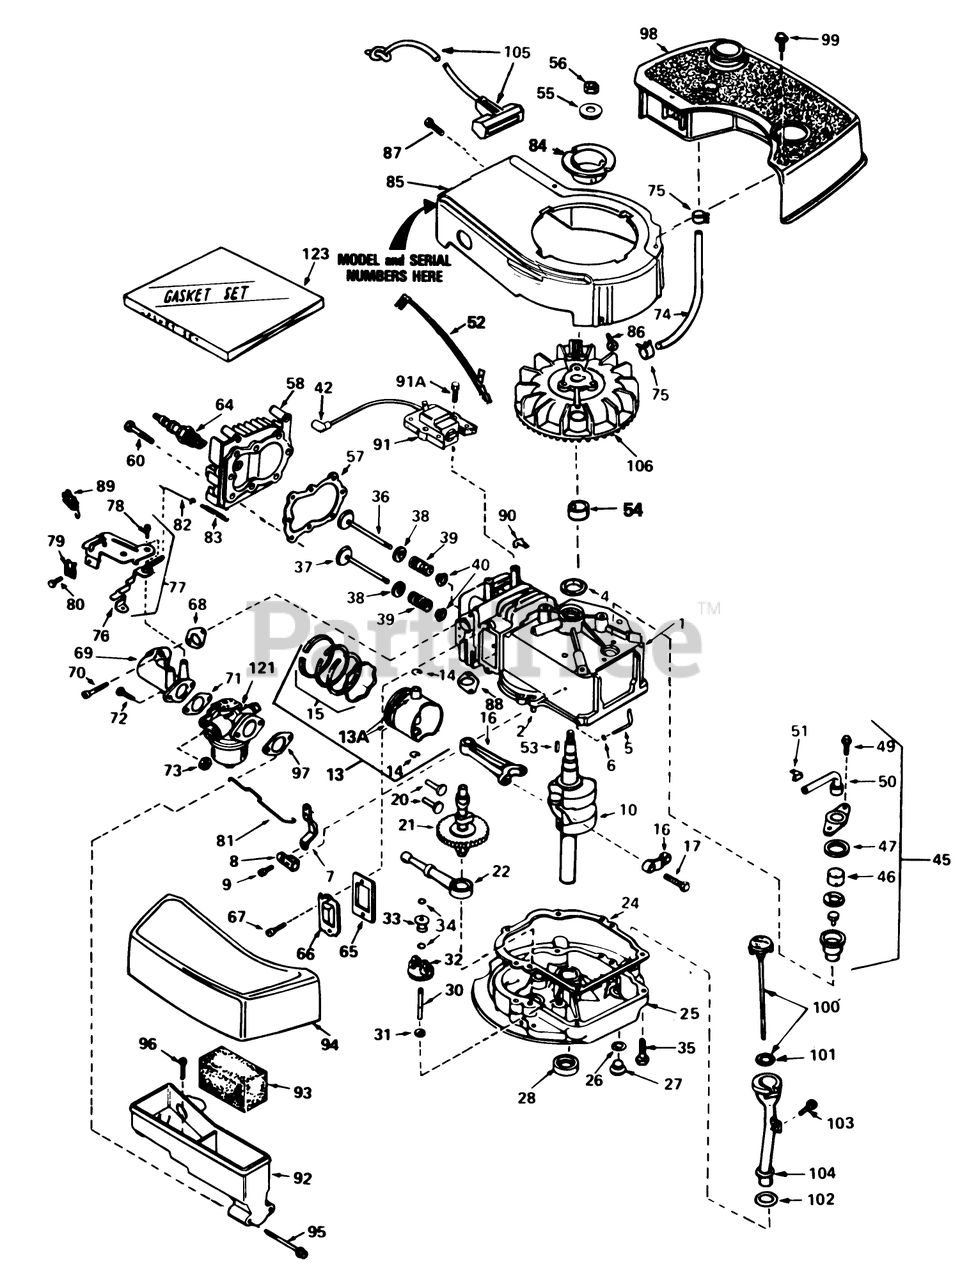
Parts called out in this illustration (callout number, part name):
1	Cyiinder Assy. (Incl. Ref. #2, 4 105)
2	Pin-Dowel
4	Seal-Oil
5	Rod, Governor (Incl. No. 36)
6	Washer-Flat
7	Governor Lever
8	Clamp-Lever, Governor
9	Screw
10	Crankshaft
13	Piston, Pin Ring Assy. (Std.) (Incl. Ref. #13A, 14 15)
13	Piston, Pin Ring Assy. (.010 oversize) (Incl. Ref. #13A, 14 15)
13	Piston, Pin Ring Assy. (.020 oversize) (Incl. Ref. #13A, 14 15)
13A	Piston Pin Assy. (Incl . Ref. . #14) (Std.)
13A	Piston Pin Assy. (Incl. Ref. #14) (.010 Oversize)
13A	Piston Pin Assy. (.020 oversize) (Incl. Ref. #14)
14	Ring-Retaining, Piston Pin
15	Ring Set (Std.)
15	Ring Set (.020" OS)
15	Ring Set (.010" OS)
16	Rod Assy., Connecting (Incl. Ref. #17)
17	Bolt-Rod, Connecting
20	Lifter-Valve
21	Camshaft(Mech.Comp. Release)
22	Oil Pump ASM
24	Gasket, Mounting
25	Flange Assy., Mounting (Incl. Ref. #26thru 30)
26	Gasket-Oil Drain
27	Plug Oil Drain
28	Seal Oil
30	Shaft-Governor
31	Washer-Flat
32	Governor Gear ASM
33	Spool-Governor
34	Ring-Retaining
35	Screw (1/4-20 x 1-1/4)
36	Valve, Intake (Std.) (Incl. Ref. #40)
36	Valve, Intake (1/32" oversize)(Incl. No. 40)
37	Valve, Exhaust (Std.)(Incl. No. 40)
37	Valve, Intake (1/32" oversize)(Incl. No. 40)
38	Cap-Upper Valve Spring
39	Spring-Valve
40	Cap-Valve, Spring
42	Cover-Spark Plug
45	Breather Assy. (Incl. Ref. #46 thru 51)
46	Element-Breather
47	Gasket-Breather
49	Screw (10-24 x 9/16)
50	Tube, Breaker
51	Clip, Breather
52	Wire-Ground
53	Key-Flywheel
54	Spacer
55	Washer-Belleville
56	Nut-Flywheel
57	63573 GIL 42 SNWTHW
58	Head-Cylinder
60	Screw (5/16-18x1-1/2)
64	Plug, Spark (J17LM or equiv.)
64	Plug, Spark (Champion RCJ-8)
65	Gasket-Breather
66	Cover-Valve
67	Screw
68	Gasket-Intake
69	Pipe, Intake (Incl. No. 68)
70	Screw (1/4-20 x 1)
71	Gasket-Carburetor
73	Nut and Lock Washer (1/4-28)
74	Line-Fuel
75	Clamp-Line, Fuel
76	Lever Control
77	Control Assy., Speed (Incl. Nos, 76, 78 89)
78	Screw, Hex Washer Hd Shoulder Self-Tap
79	Conduit
80	Screw (10-32 x 3/8)
81	Link-Throttle
82	Link Governor Spring
83	Spring Governor
84	Hub-Starter
85	Housing Blower
86	Screw (1/4-20x19/32)
87	Screw (10-24 x 9/16)
88	Gasket Exhaust
89	Terminal
90	Clip-Wire
91	Solid State
91A	Screw
92	Body Air Cleaner
93	Filer, Air
94	Cove, Air Cleaner
95	Screw Fil Hd.
96	Screw, Hex Hd.
97	Gasket-Air Cleaner
98	Tank-Fuel
99	Screw (10-32 x 35/64)
100	Dipstick, Oil (Incl. Ref. #101)(Twist Lock)
101	O-Ring
102	Gasket
103	Screw (10-32 x 1/2)
104	Tube-Oil Fill
105	Rope Assy., Starter
106	Flywheel
121	Carburetor (Incl. Ref. #71)
123	Gasket Set
